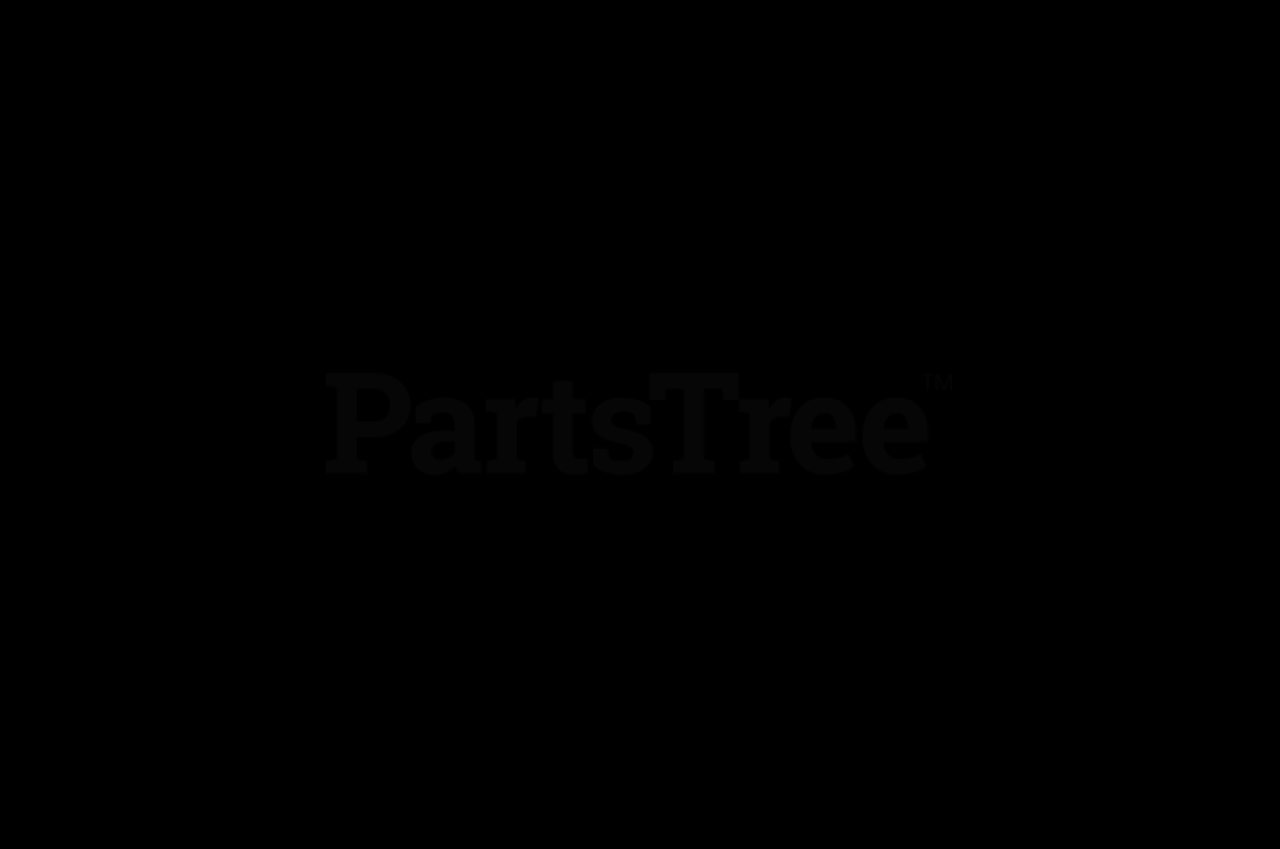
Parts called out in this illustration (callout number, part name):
1	Tank, Right Hand Fuel
2	Bolt, Hex .31-18 x .75
3	Hose, .31 ID
4	Clamp, Hose Wire .52/.55
5	Tank, Left Hand Fuel
6	Valve, Fuel
7	Cap, Fuel
8	Grommet, Orange
9	Fitting, Tank
10	Fitting, Tank
11	26" Fuel Line Kit, Diesel (Inside Tank)
12	Washer, Steel .38 x .875 x .83
13	Washer, Lock .31 x .078
